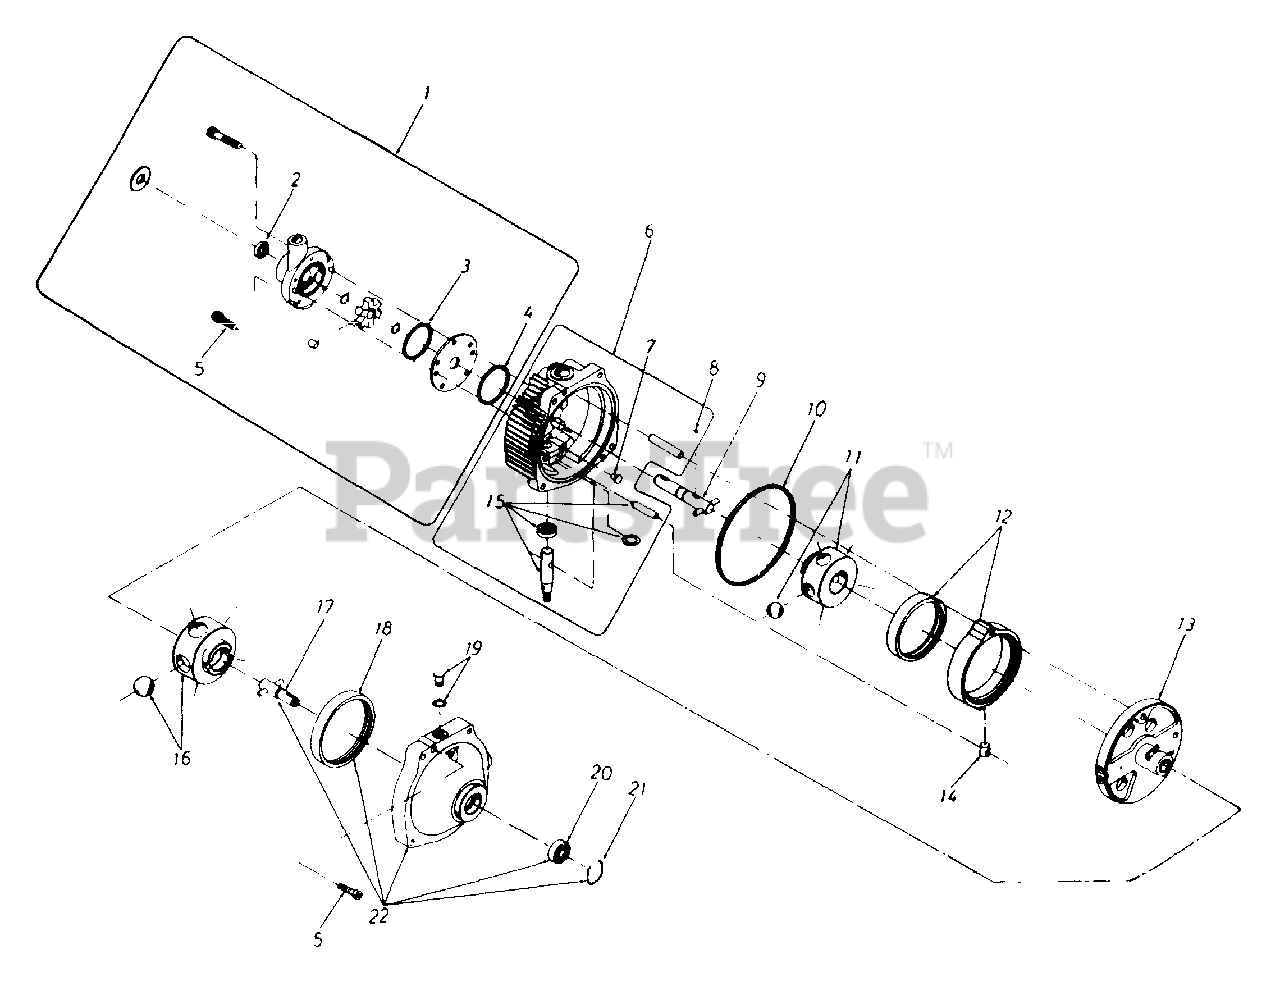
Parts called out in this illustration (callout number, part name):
1	Charge Pump Kit
2	Oil Seal
3	Square Cut Seal Ring .036
4	Square Cut Seal Ring .038
5	Socket Head Cap Screw 5/16-18 x 1.25" Long
6	Cover Subassembly
7	Button
8	Drive Pin
9	Input Shaft Subassembly
10	Square Cut Seal Ring .166
11	Pump Rotor - Ball Subassembly
12	Cam Ring Subassembly
13	Pintle Subassembly
14	Cam Ring Insert
15	Control Shaft Kit
16	Motor Rotor - Ball Subassembly
17	Output Shaft Subassembly
19	"O"-Ring Plug Subassembly
20	Ball Bearing (Output)
21	Retaining Ring
22	Body Subassembly
